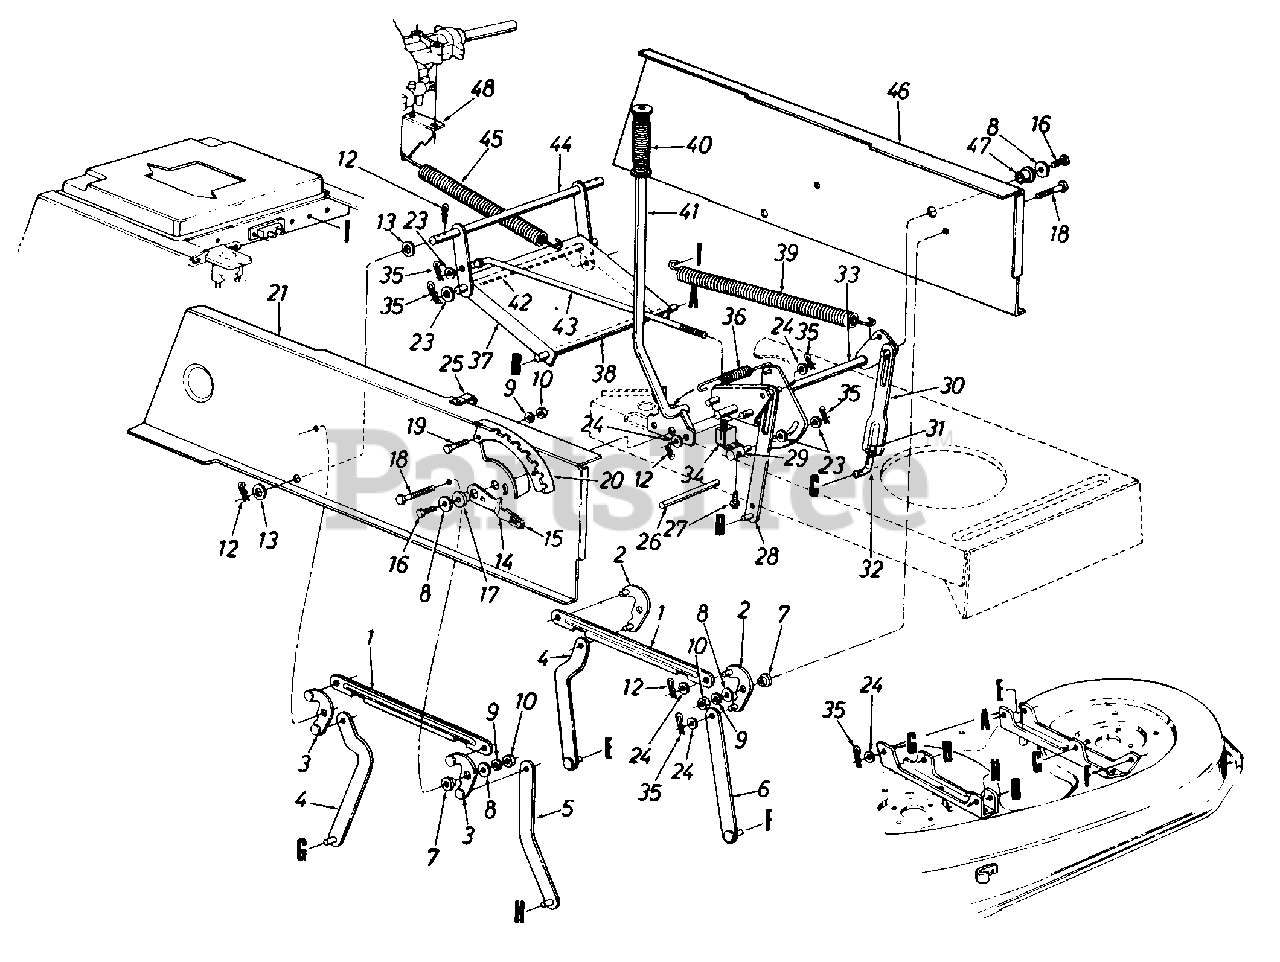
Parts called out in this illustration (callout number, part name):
1	Connecting Rod
2	Pivot Link Ass'y. L.H.
3	Pivot Link Ass'y. R.H.
7	Shld. Spacer .3/8" I.D.
8	Fl-Wash. .344" I.D. x 1.125"
9	L-Wash. 5/16" I.D.
10	Hex Nut 5/16-18 Thd.
12	Cotter Pin 1/8" Dia.
13	Fl-Wash. .635" I.D. x 1.0" O.D.
14	Deck Lift Down Stop
15	Knob
16	Hex Wash. TT-Tap Scr. 5/16-18 x .75" Lg.
17	Flange Brg. .63" I.D.
18	Hex Wash. TT-Tap Scr. 5/16-18 x.875" Lg.
19	Hex Bolt 5/16-18 x .75" Lg.
20	Index Brkt.
21	Upper Frame R.H.
23	Fl-Wash. .385" I.D. x .87" O.D.
24	Fl-Wash. .531" I.D. x .93" O.D.
25	Clamp
26	Running Board Rod
27	Truss Mach. Scr. #10 x .5" Lg.
31	Hex Nut 1/2-20 Thd. (Grade 5)
32	Lift Link Adjuster
33	Lift Shaft Ass'y.
34	Safety Switch (Deck)
35	Inter. Cotter Pin 3/8" Dia.
36	Extension Spring
37	Stabilizer Bracket
38	Shaft 1/2" Dia. x 10.28" Lg.
39	Extension Spring
40	Grip
41	Deck Lift Handle Ass'y.
42	Shaft 3/8" Dia. x 9.34" Lg.
43	Disengagement Rod
44	Stabilizer Shaft Ass'y.
45	Extension Spring 7.58" Lg.
46	Upper Frame L.H.
47	Flange Brg. .632" I.D.
48	Spring Retainer Brkt.
